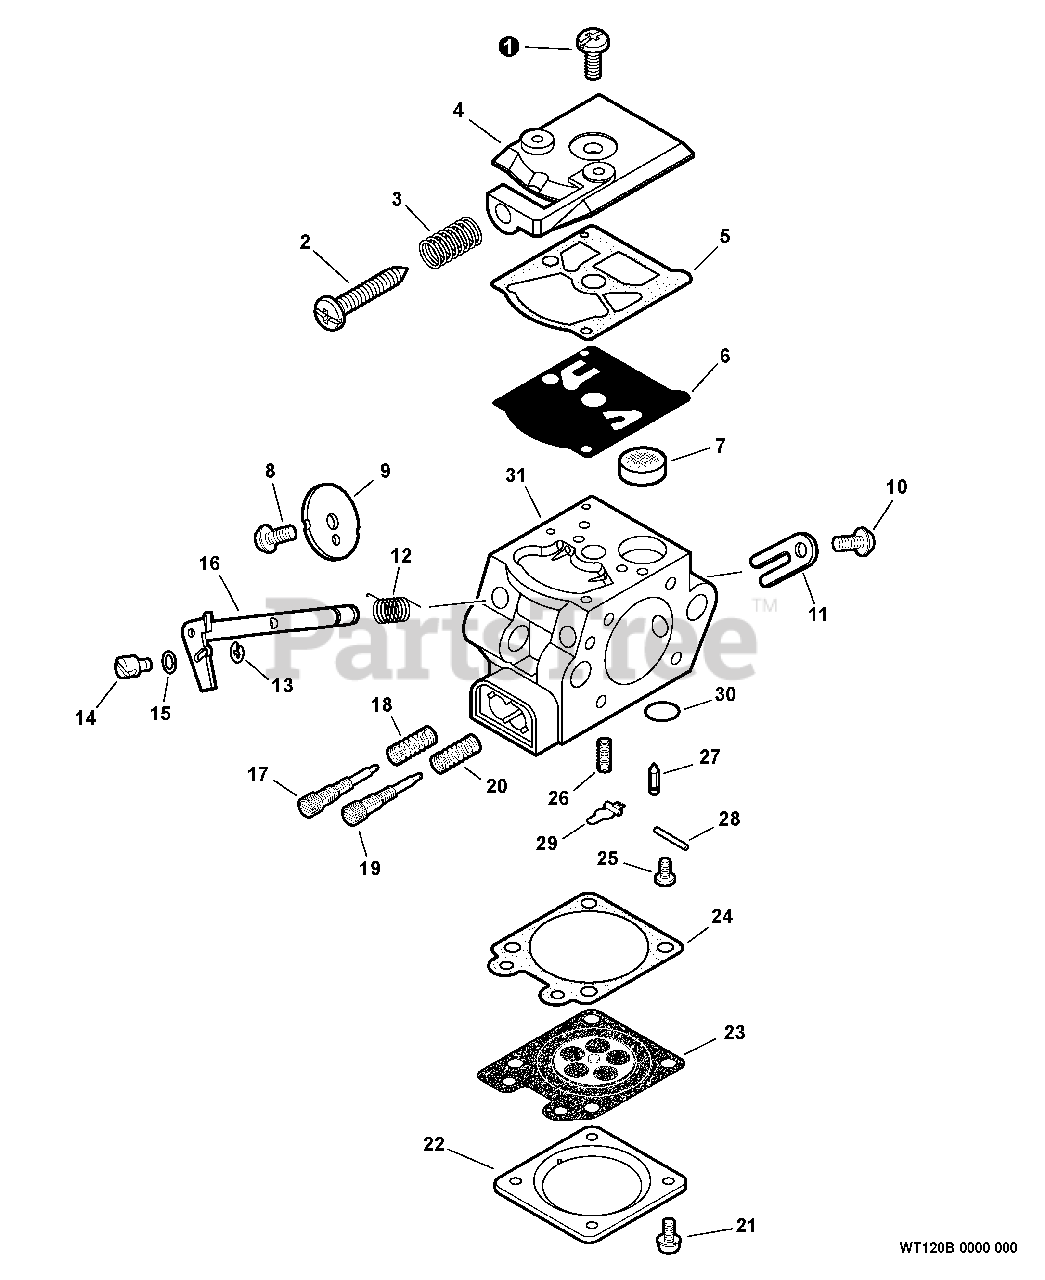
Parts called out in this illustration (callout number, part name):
2	SCREW, IDLE ADJUST
4	COVER, FUEL PUMP
5	GASKET, FUEL PUMP
6	DIAPHRAGM, PUMP
7	SCREEN, FUEL INLET
9	VALVE, THROTTLE
11	CLIP, THROTTLE SHAFT
12	SPRING, THROTTLE
16	SHAFT, THROTTLE
17	NEEDLE, LOW SPEED
18	SPRING, NEEDLE
19	NEEDLE, HIGH SPEED
20	SPRING, HIGH NEEDLE
22	COVER, METERING DIAPHRAGM
23	DIAPHRAGM, METERING
24	GASKET, METERING DIAPHRAGM
25	SCREW, METERING LEVER PIN
27	VALVE, INLET NEEDLE
28	PIN, METERING LEVER
29	LEVER, METERING
30	PLUG, WELCH
31	BODY, CARBURETOR
